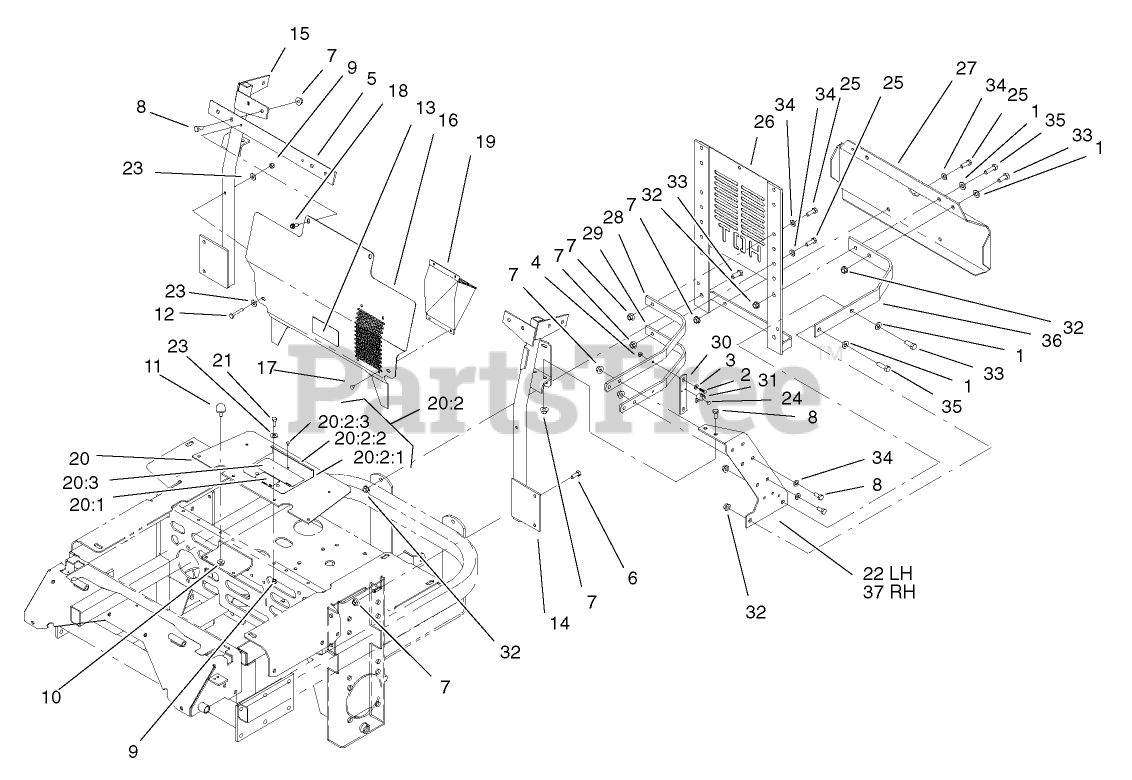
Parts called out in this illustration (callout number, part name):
1	WASHER-FLAT
2	SCREW
3	WASHER-FLAT
4	NUT-LOCK, NI
5	CROSSBAR
6	SCREW-HH
7	NUT-HF
8	SCREW-HH
9	NUT-LOCK, NI
10	NUT-HF
11	BUMPER
12	SCREW-HH
13	DECAL-ROUTING, BELT
14	Brace-Radiator, LH
15	BRACE-RADIATOR, RH
16	Deflector-Air
17	RIVET-POP
18	SCREW-HWHTF
19	Plenum-Intake, Air
20	SHIELD ASM
20:1	DECAL-IMPORTANT
20:2	SHIELD AND LIFT ASM
20:2:1	SHIELD-ENGINE
20:2:2	LIFT-SHIELD
20:2:3	RIVET-POP
20:3	DECAL-DEVICES, ROTATING
21	SCREW-HH
22	PLATE-SIDE, LH
23	WASHER-FLAT
24	RIVET
25	SCREW-HH
26	MOUNT-RADIATOR, REAR
27	GUARD-BUMPER
29	RIB-BOTTOM
30	BAR-HOOK, LATCH
31	KEEPER-LATCH, RUBBER
32	NUT-HHF, WHIZ
33	SCREW-HH
34	WASHER-PLAIN
35	SCREW-HH
36	BAR-RADIATOR MOUNT FRAME
37	PLATE-SIDE, RH
